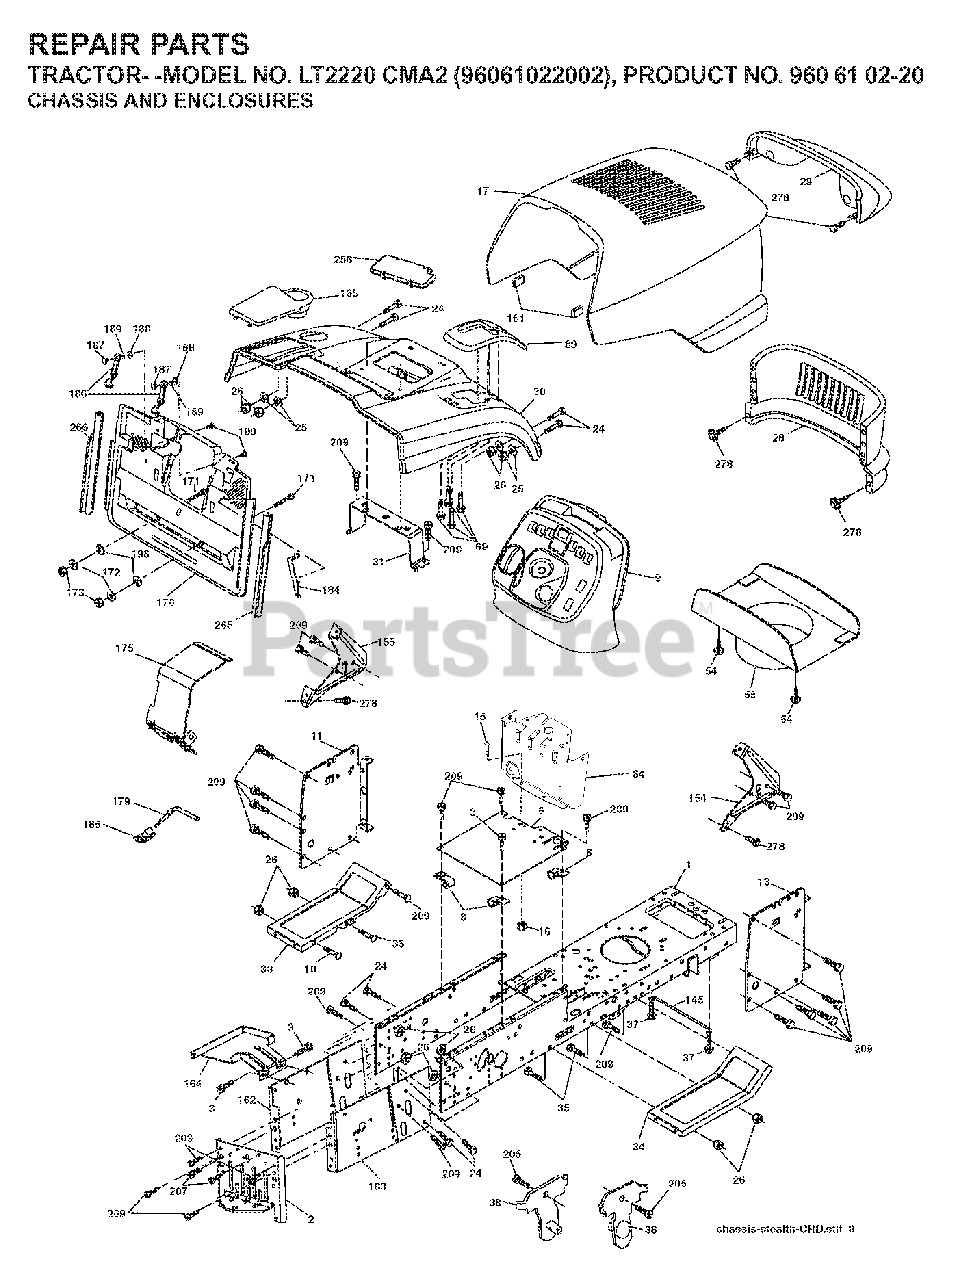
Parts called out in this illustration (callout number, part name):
1	CHASSIS
3	SCREW 3/8-16X3/4
8	CLIP,INSULATOR
10	BOLT D
13	PANEL DASH RH
16	NUT
24	BOLT
25	WASHER
26	NUT
31	BRACKET SUPPORT FENDER
35	BOLT
37	SCREW LT
54	SCREW.WSHD.HEX10-32X5/8
58	DUCT HOOD
69	SCREW.HI-LO.CONSOLE
145	ROD.PIVOT.HOOD
161	EXTRUSION BUMPER
164	SUPPORT
171	BOLT
172	WASHER
186	LATCH ASSY
187	WELDNUT
189	LOCKWASHER
190	SCREW
205	SCREW LT
207	SCREW, 5/16-18 X 1/2
209	SCREW, 3/8-16X3/4
278	SCREW.#10 X 0.750.BOS THREAD
